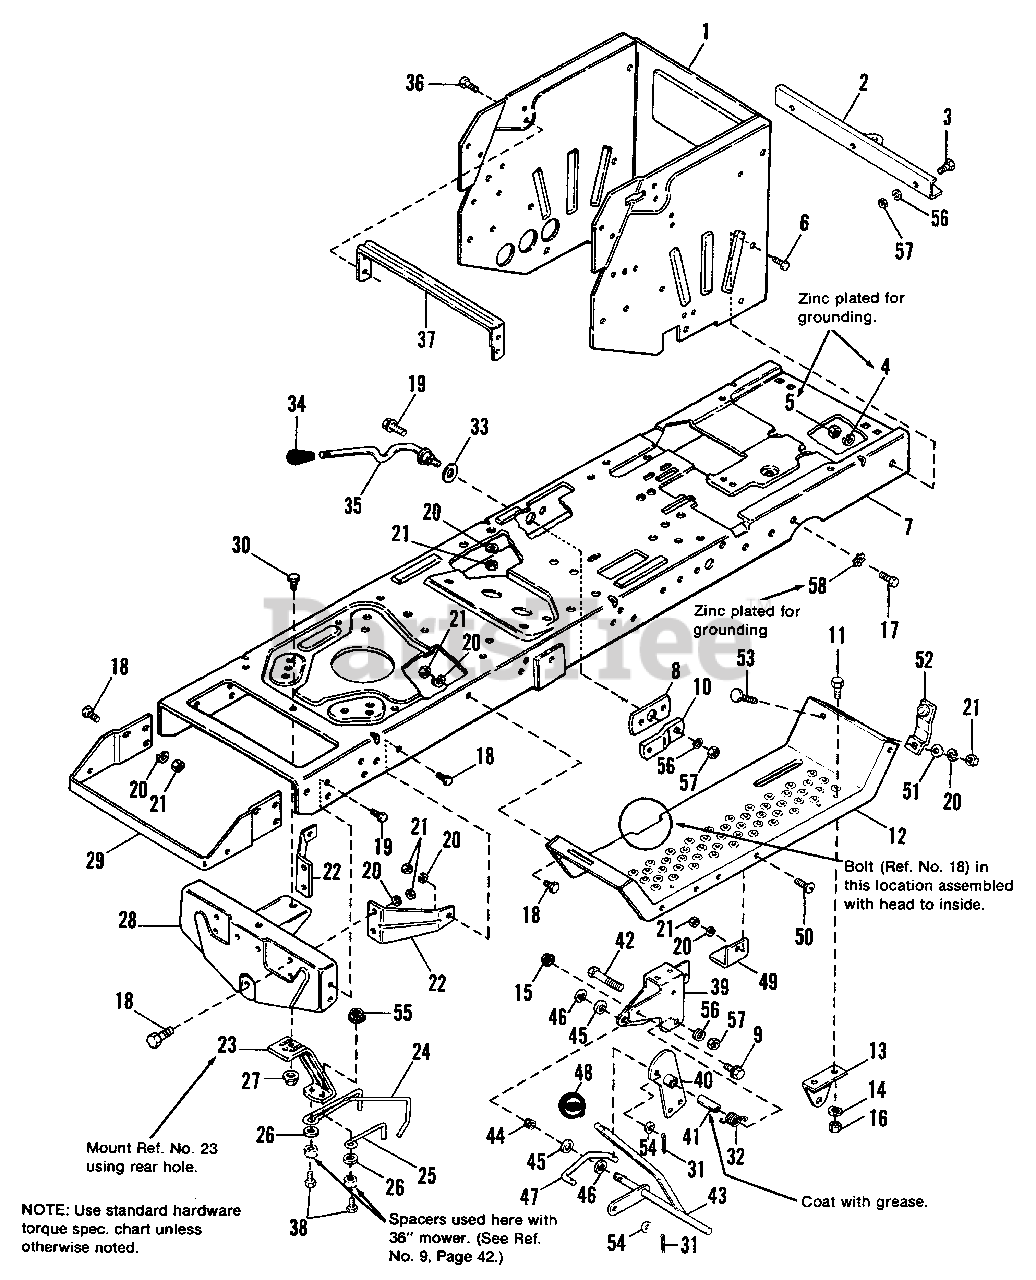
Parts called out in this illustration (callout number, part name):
1	SUPPORT, Axle, Wrapper
2	BAR, Draw
3	CAPSCREW, Hex Hd., 3/8-16 x 1
4	LOCKWASHER, 3/8, Zinc Pltd.
5	NUT, Hex, Full, 3/8-16 (Zinc pltd.)
6	CAPSCREW, Hex Hd., 3/8-16 x 1-1/2
8	BAR, Support
9	CAPSCREW, Hex Wash. Hd., 1/4-20 x 5/8
10	ARM, Support
11	CAPSCREW, Hex Hd., 1/4-20 x 5/8
13	SUPPORT, Clutch
14	LOCKWASHER, 1/4
15	NUT, Flange, Whizlock, 1/4-20
16	NUT, Hex, 1/4-20
17	CAPSCREW, 3/8-16 x 3/4
18	CAPSCREW, Hex Hd., 5/16-18 x 3/4
19	SCREW, Hex Taptite, 5/16-18 x 3/4
20	LOCKWASHER, 5/16
21	NUT, Hex, Full, 5/16-18
22	BRACE, Axle Support
26	WASHER, Plain, 1/4
27	NUT, Flange, Whizlock/5/16-18
28	SUPPORT, Axle
29	SUPPORT, Hood
30	SCREW, Hex Hd., Flange, Whizlock, 5/16-18 x 1-1/4
31	PIN, Cotter, 3/32 x 3/4
34	GRIP
35	HANDLE, Lift
36	SCREW, Hex, Washer Hd., Taptite, 5/16-18 x 1/2
37	BRACE, Seat
38	CAPSCREW, 5/16-18 x 1-1/2
39	BRACKET, P.T.O.
40	ARM ASSY., P.T.O. Rod
42	CAPSCREW, Hex Hd., 3/8-16 x 2/1-4
43	HANDLE ASSY., P.T.O.
45	WASHER on P.T.O. Link
46	RING, Snap
47	LINK, P.T.O.
49	UP-STOP, Mower
50	SCREW, Truss Hd., Slotted, 5/16-18 x 3/4
52	LATCH ASSY.
53	BOLT, Carriage, 5/16-18 x 3/4
54	WASHER
55	NUT, Lock, Flange 5/16-18
56	LOCKWASHER, 3/8
57	NUT, Hex, 3/8-16
58	LOCKWASHER, Ext. 3/8, Zinc Pltd.
